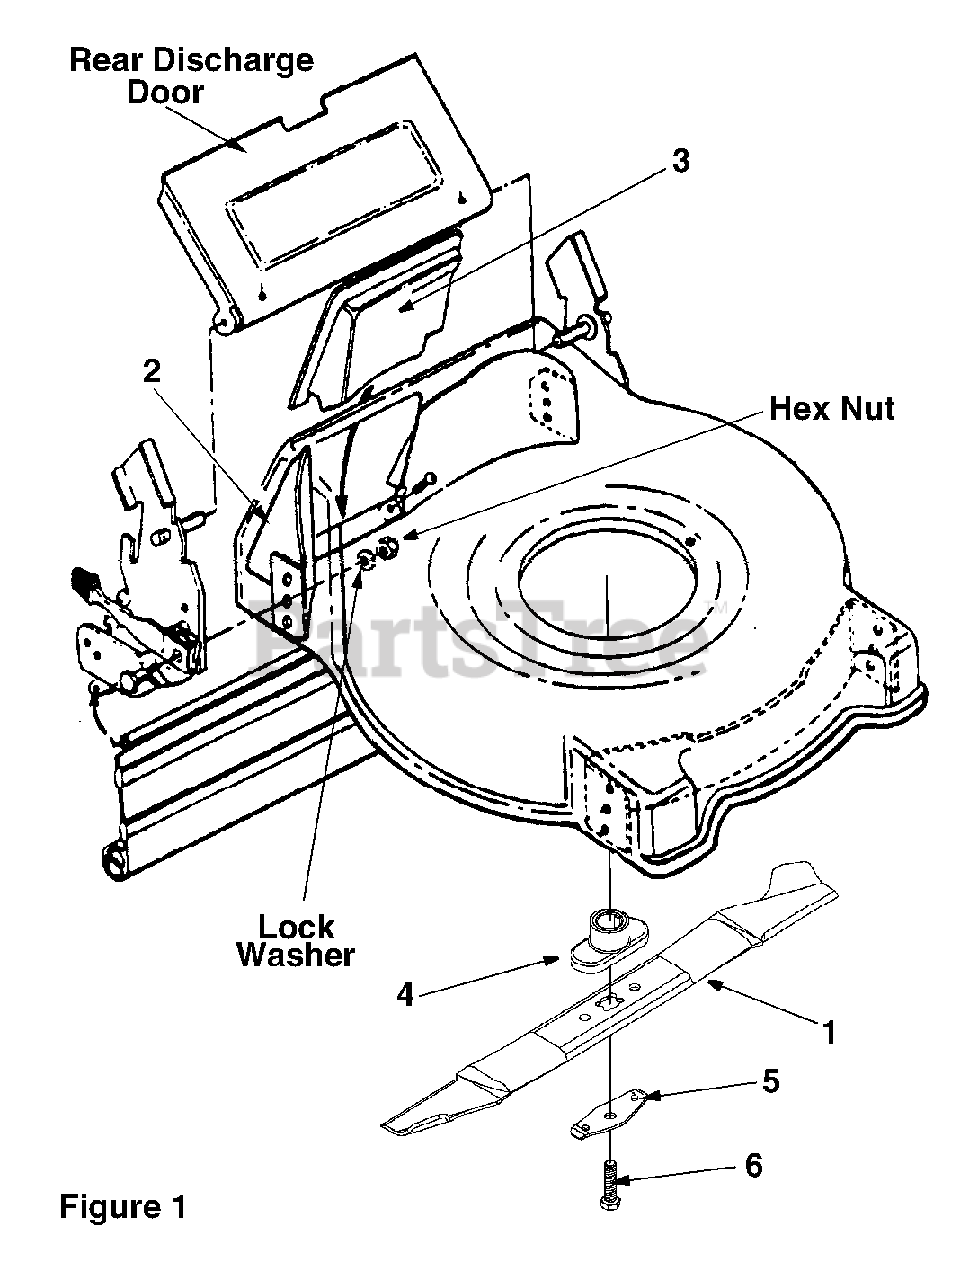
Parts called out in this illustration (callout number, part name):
1	21" Mulching blade
4	Star blade adapter
5	Blade bell support
6	Center bolt
